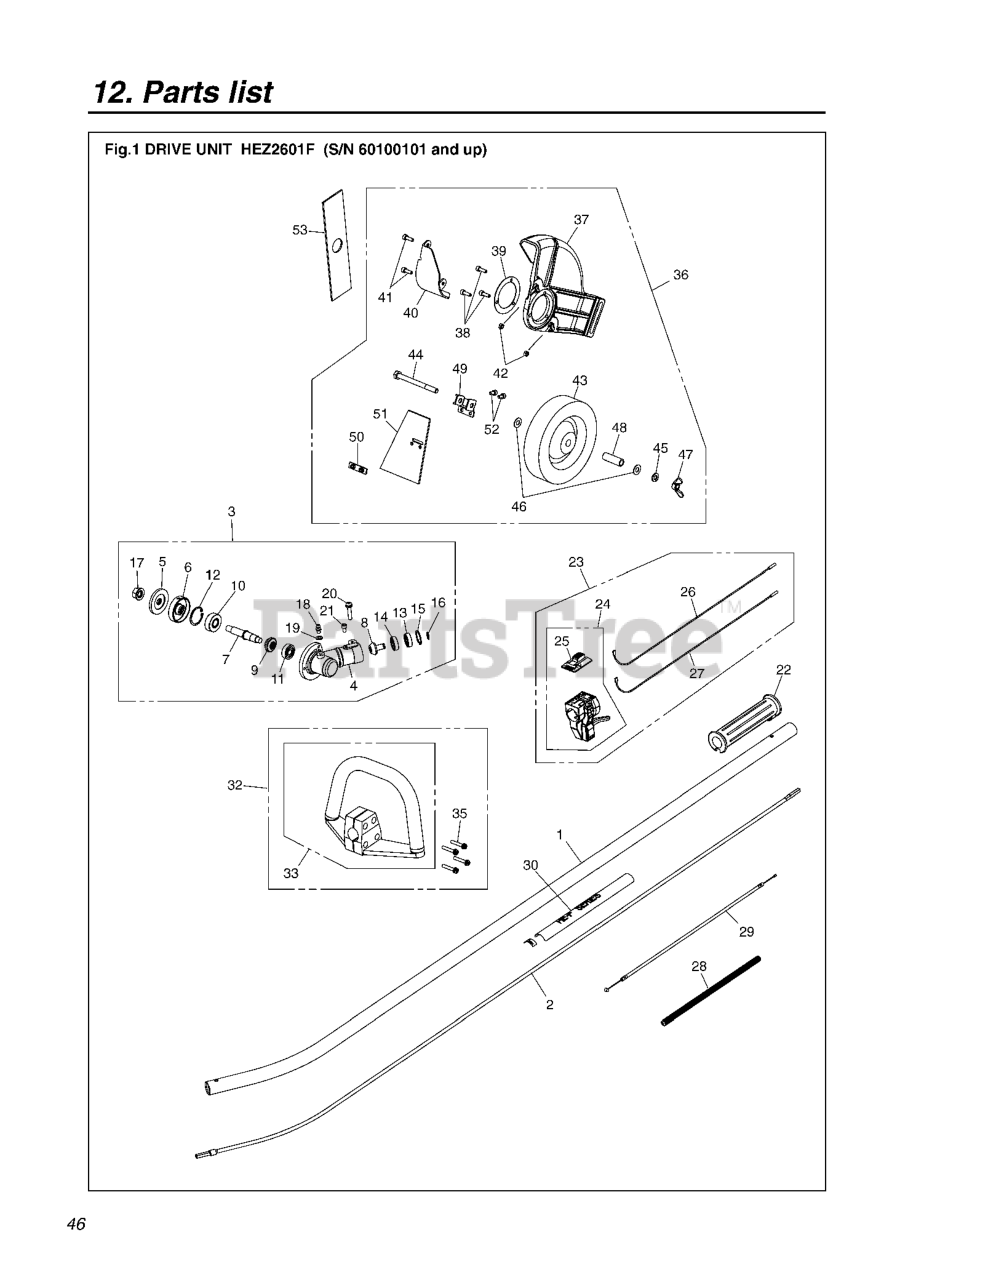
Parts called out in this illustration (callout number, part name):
1	PIPE COMP
2	FLEX SHAFT
3	GEARCASE ASSY
4	GEARCASE
5	HOLDER(B)
6	HOLDER(A)
7	SHAFT.GEAR
10	BEARING***
21	BOLT M5 X L10 ALLEN BOLT
23	LEVER COMP (RPLS 8488R20343)
24	LEVER (FLEX. LEVER)(RPLS -13)
25	COVER COMP (RPLS 611014410-02)
26	CORD (A), BLACK
27	CORD (B), RED
32	HANDLE ASSY. (RPLS T319514001)
33	HANDLE T
36	GUARD ASSY.
38	BOLT M5 X L16 ALLEN
40	PROTECTOR
41	BOLT M5 X L16 ALLEN
47	RP_NUT
52	BOLT M5 X L10 ALLEN BOLT
